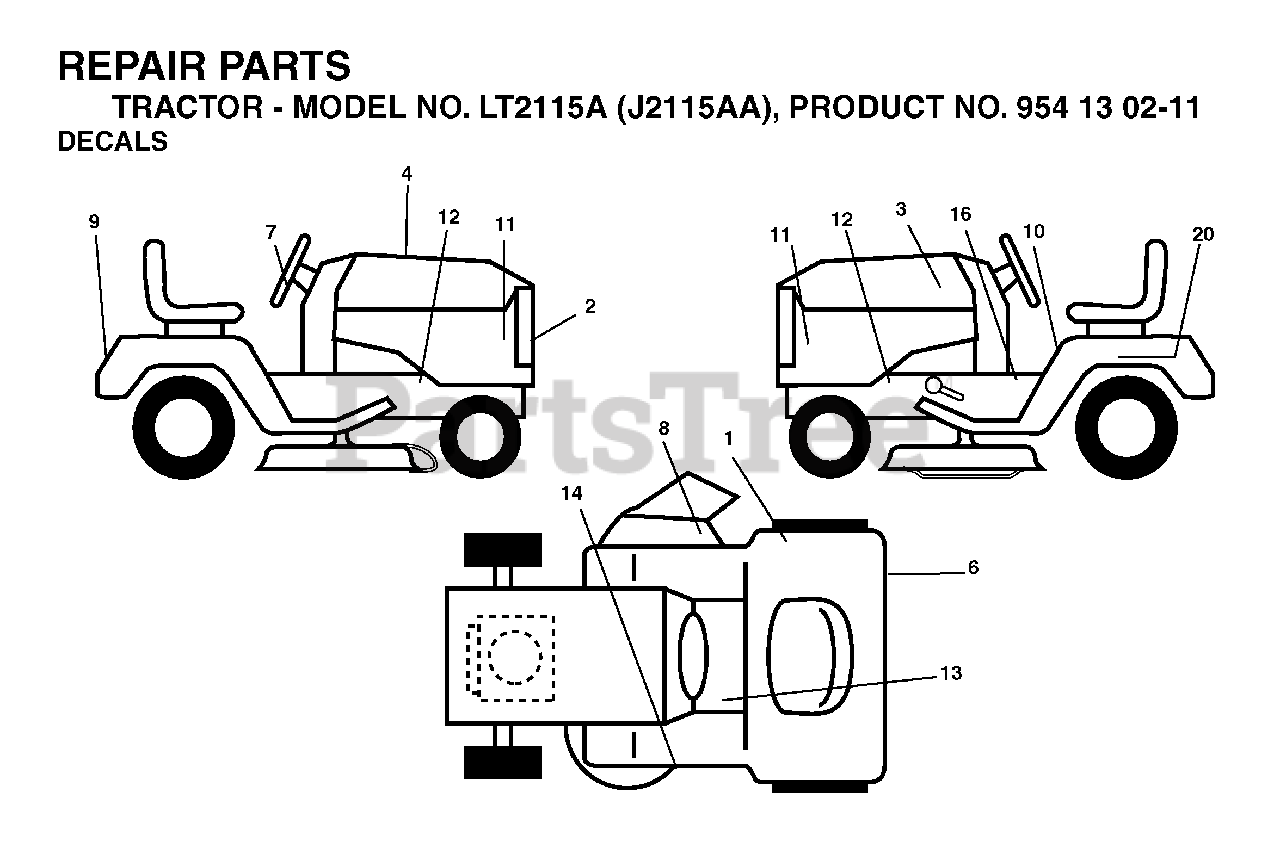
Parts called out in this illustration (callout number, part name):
8	DECAL.INTERNATIONL.CUTFINGER
10	DECAL READ OWNER'S MAN SYMS
14	DECAL V-BELT SCHEMATIC
16	DECAL PARK BRAKE
20	DECAL BTRY SYMBOLS
